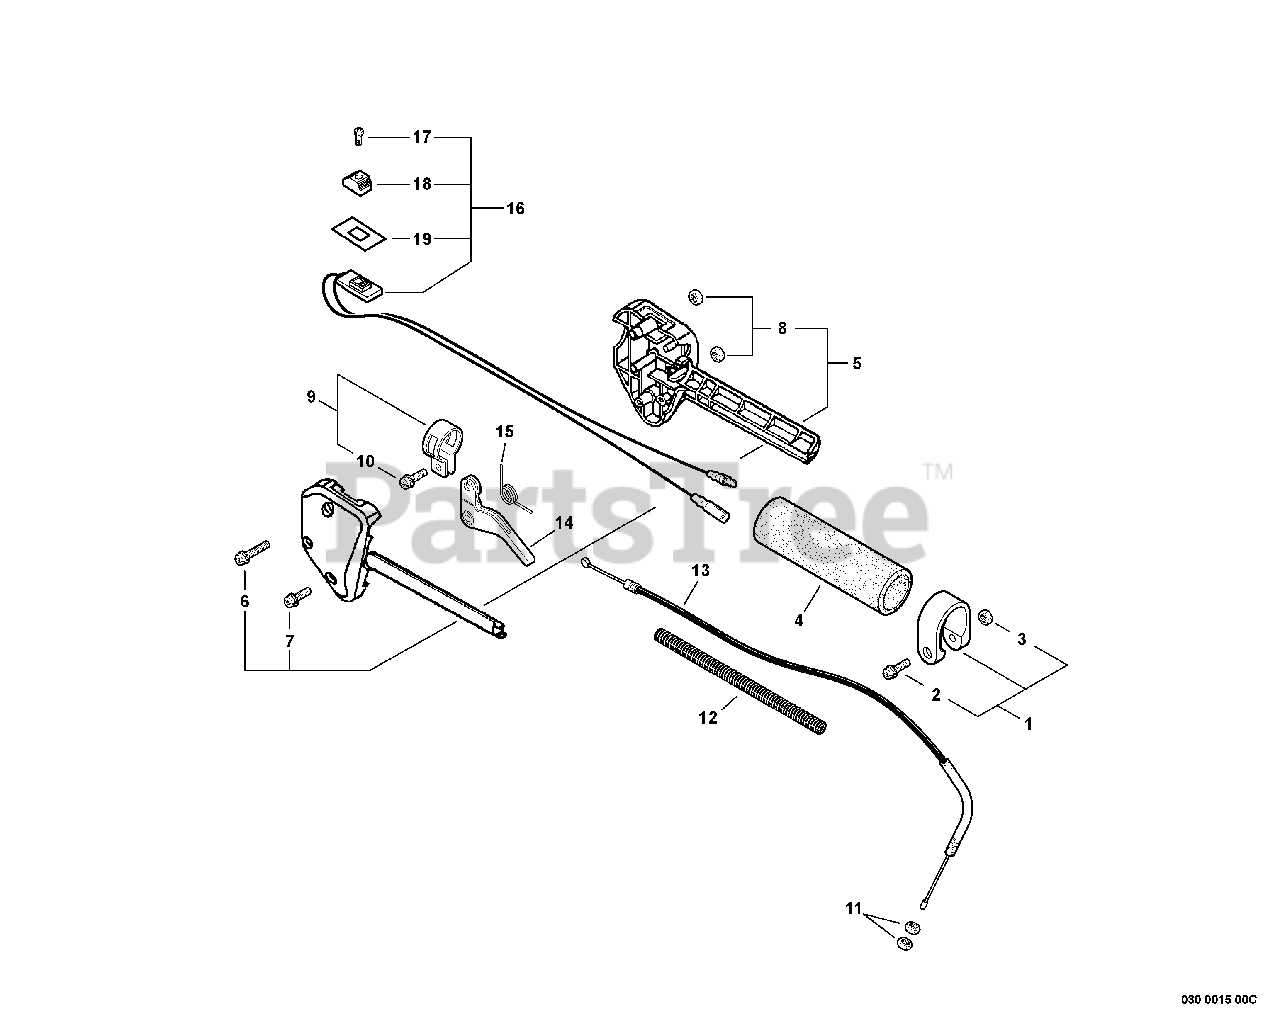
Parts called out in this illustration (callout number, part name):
1	CLAMP KIT
2	SCREW 5×28
3	NUT M5
4	GRIP, HANDLE
5	HANDLE KIT, CONTROL
6	SCREW 5×35
7	SCREW 5×25
8	NUT M5
9	CLAMP KIT
10	SCREW 5×14
13	CABLE, THROTTLE
14	TRIGGER, THROTTLE
15	SPRING, TORSION
16	SWITCH ASSY, ON-OFF
17	SCREW 3×10
18	KNOB, SWITCH - ORANGE
19	LABEL, SWITCH
